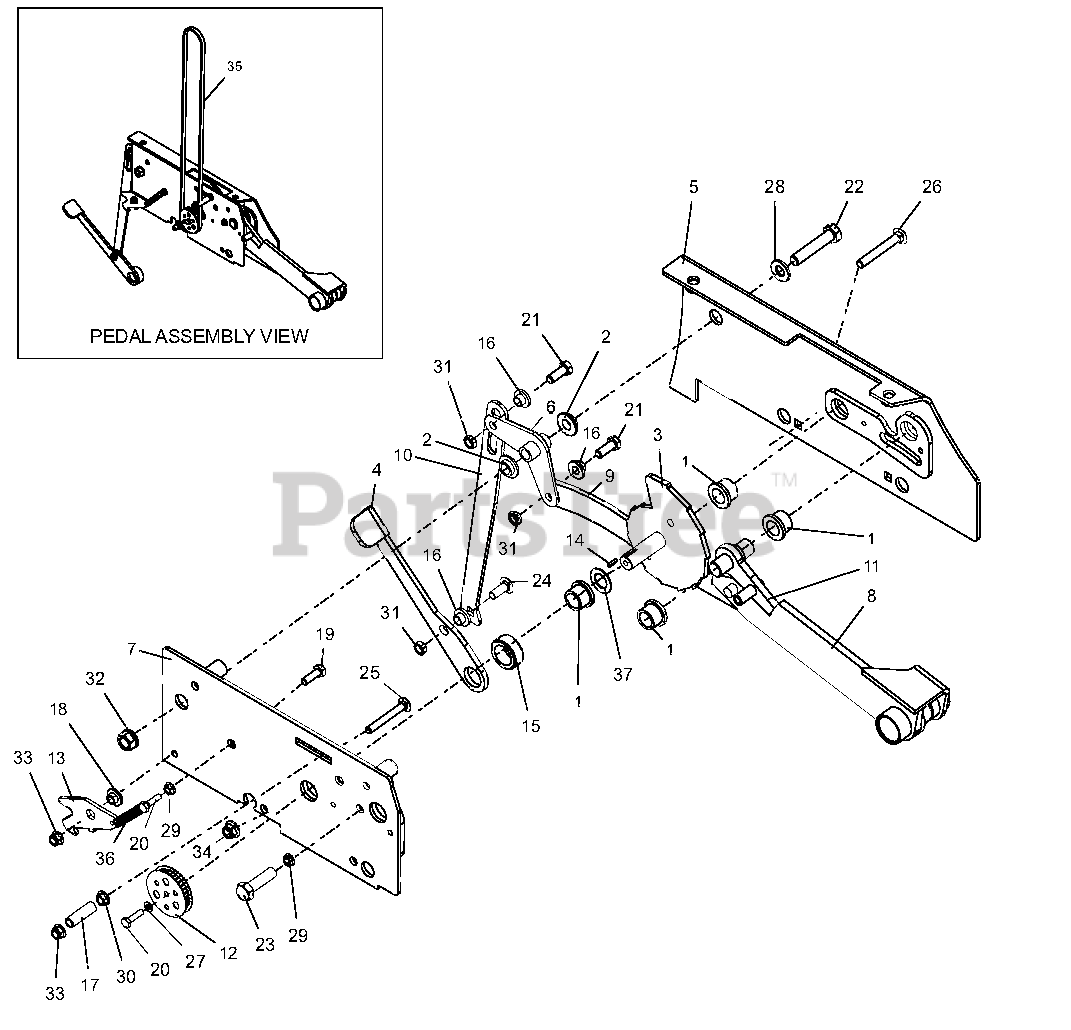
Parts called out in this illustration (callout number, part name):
1	BUSHING, .750 X 1.00 X .750
2	BSHG-FLG .515 X .750 X .395 X 1.120
3	WLDMT, HEIGHT OF CUT
4	ARM, LOWER TURN
5	WLDMT, LH BOTTOM TOWER SIDE
6	WLDMT, REAR PIVOT
7	WLDMT, CAM COVER
8	WLDMT, CAM CONTACT
9	WLDMT, DECK LIFT LINK
10	ARM, PEDAL
11	WLDMT, TRAILER LOCK
12	WLDMT, PULLEY
13	LATCH, FOOT PEDAL
14	KEY, .125 SQ X .50
15	SPCR, 1.032 X 1.5 X .594
16	BSHG-FLG .385 X .500 X .875 X .406 REV
17	BUSHG, SLV .33 X .50 X 1.56
18	BSHG. -FLG .312 X .500 X .344
19	BLT-HEX .31-18 X 1.00 GR5 YWZC
20	BLT-HEX .25-20 X 1.00 GR5 YWZC
21	BLT-HEX .38-16 X 1.00 GR5 YWZC
22	BLT-HEX .50-13 X 2.75 GR5 YWZC
23	BLT-HEX .25-20 X .75 GR5 YWZC
24	BLT-RDHDSHSQNK .38-16 X 1.0 G5YZ
25	BLT-RDHDSQNK .31-18 X 2.50 G5 Y
26	BLT-RDHDSQNK .38-16 X 2.75 G5 Y
27	WSHR-LK .25X .062 REG YWZC
28	WSHR-FL-STL .531 X 1.06 X .095 YWZC
29	NUT-LK-FLG .25-20 YWZC
30	NUT-SPNLK-FLG .312-18 YWZC
31	NUT-LK-CTR-JAM .375-16 YWZC
32	NUT, LK-TOPFLG .50-13 YWZC
33	NUT-LK-NYL-FLG .31-18 YWZC
34	NUT-LK-NYL-FLG .38-16 YWZC
35	BELT, TIMING
36	SPRG, EXTENSION
37	BUSHING, MACH .75 X 1.25 X .048
